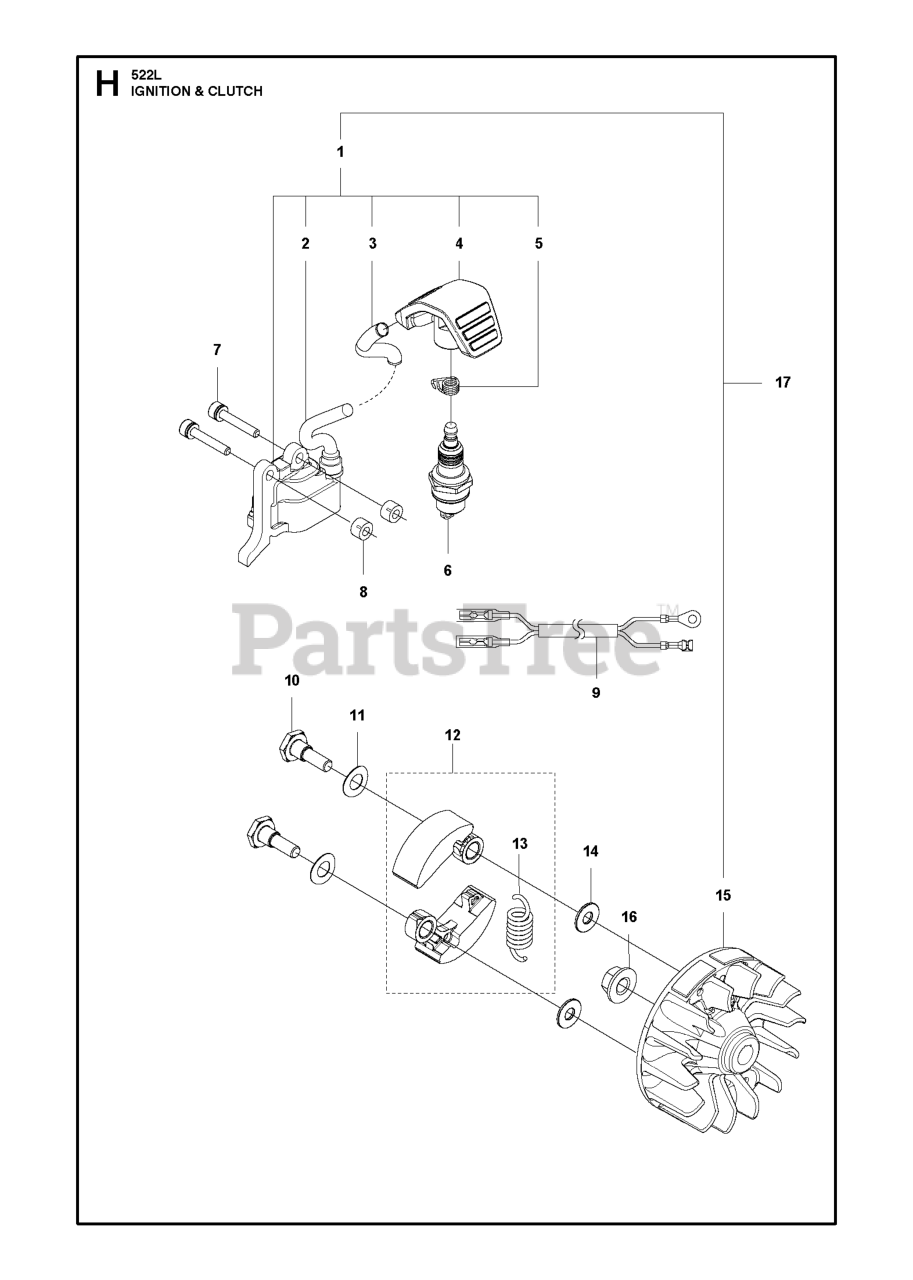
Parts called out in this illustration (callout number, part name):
6	SPARK PLUG NGK BPMR-8Y
9	SHORT CIRCUIT CABLE
12	CLUTCH ASSY
13	CLUTCH SPRING
17	IGNITION MODULE ASSY
